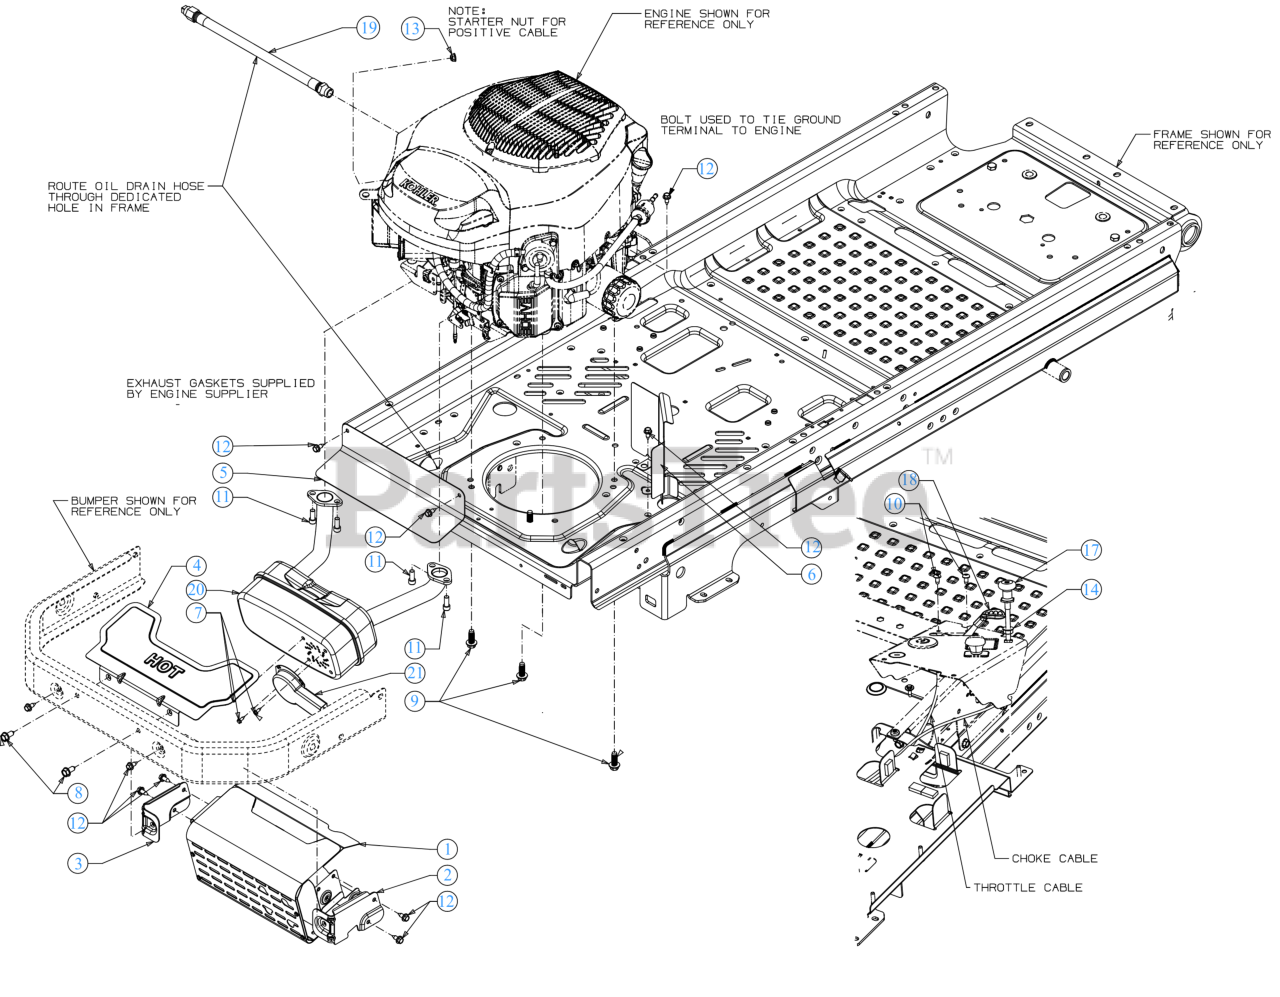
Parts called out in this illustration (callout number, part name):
5	LOWER HEAT SHIELD
6	ENGINE HEAT SHIELD
7	HEX SCREW WASHER HD #8-18 x 0.500
8	SCREW 5/16-18 x .750
9	SCREW 3/8-16 x 1
10	SCREW 1/4-20 x .5
11	HEX FLANGE NUT M8X
12	SCREW 1/4-20X.625
13	FLANGE LOCK NUT
14	HEX FLANGE NUT
17	61" CHOKE CABLE
18	THROTTLE CABLE 59"
19	OIL DRAIN HOSE
20	EXHAUST MUFFLER (KH TWIN)
21	EXHAUST DELECTOR (LONG)
